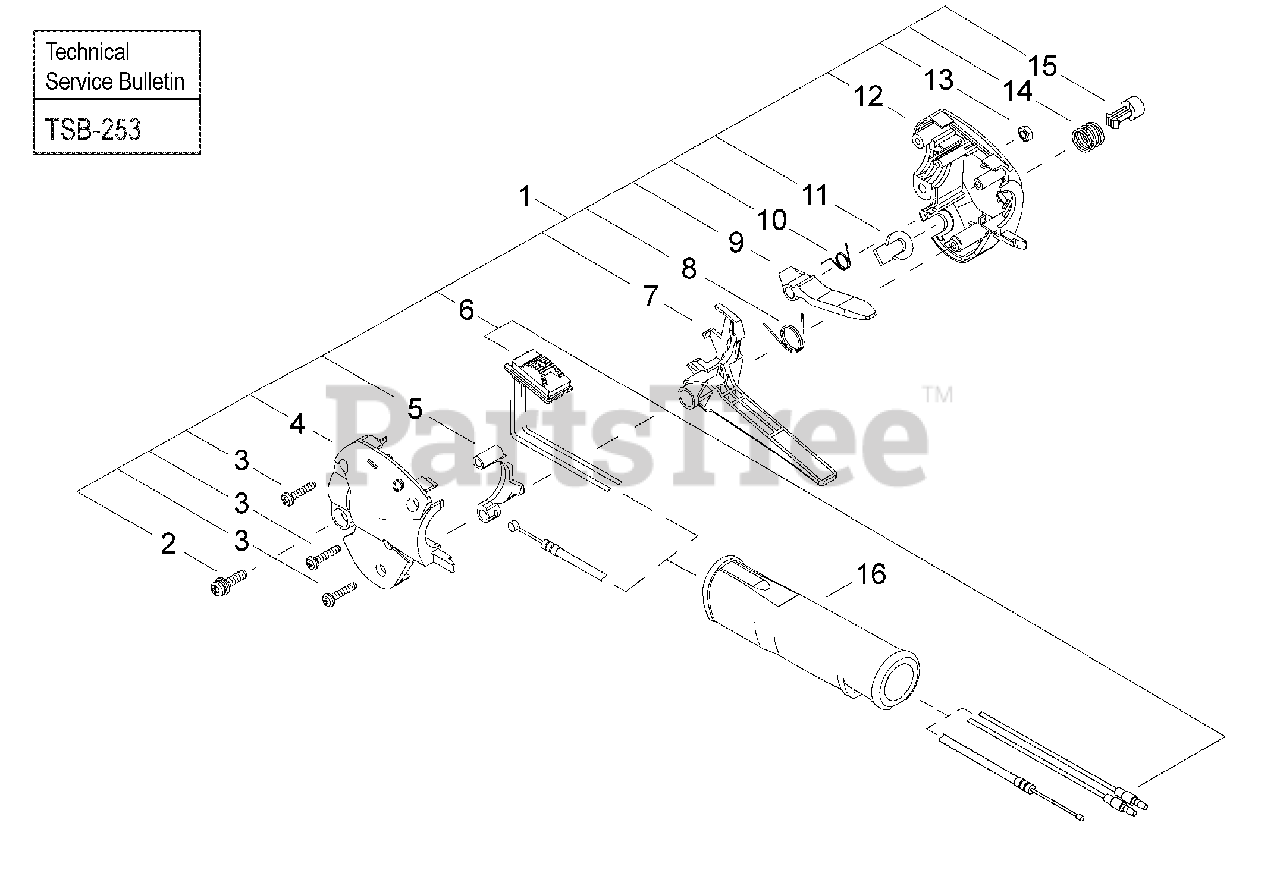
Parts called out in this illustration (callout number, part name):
1	THROTTLE CONTROL ASSY
2	SCREW M5×20
3	SCREW, TAPPING M4×20
4	CONTROL HANDLE - LEFT
5	LOCKOUT, THROTTLE
6	SWITCH, ON-OFF
7	TRIGGER, THROTTLE
8	SPRING, THROTTLE RETURN
9	LEVER, THROTTLE LOCKOUT
10	SPRING, THROTTLE LOCKOUT
11	PLUG
12	CONTROL HANDLE - RIGHT
13	NUT M5
14	SPRING, COMPRESSION
15	BUTTON, THROTTLE LOCK
16	GRIP, REAR
